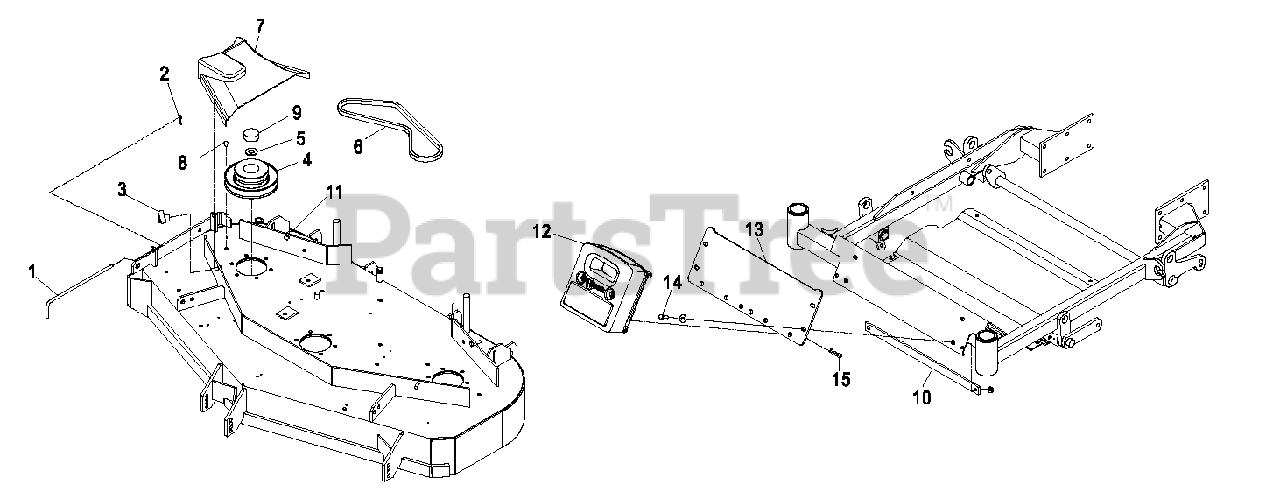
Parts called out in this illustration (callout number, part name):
1	PIN, CHUTE PIVOT
2	PIN-COTTER
3	KNOB-3 PRONG
4	SHEAVE, BLOWER DRIVE 50
5	WASHER-FLAT
6	BELT, BLOWER DRIVE 60
7	COVER, BELT 50
8	SCREW-HH
9	PLUG, BLACK NYLON 1.75
10	STRAP,WEIGHT MOUNT
11	BOLT-CARR
12	ASM,CAST WEIGHT
13	PLATE,WEIGHT ASM MOUNT
14	SCREW-HH
15	PIN-HAIR
